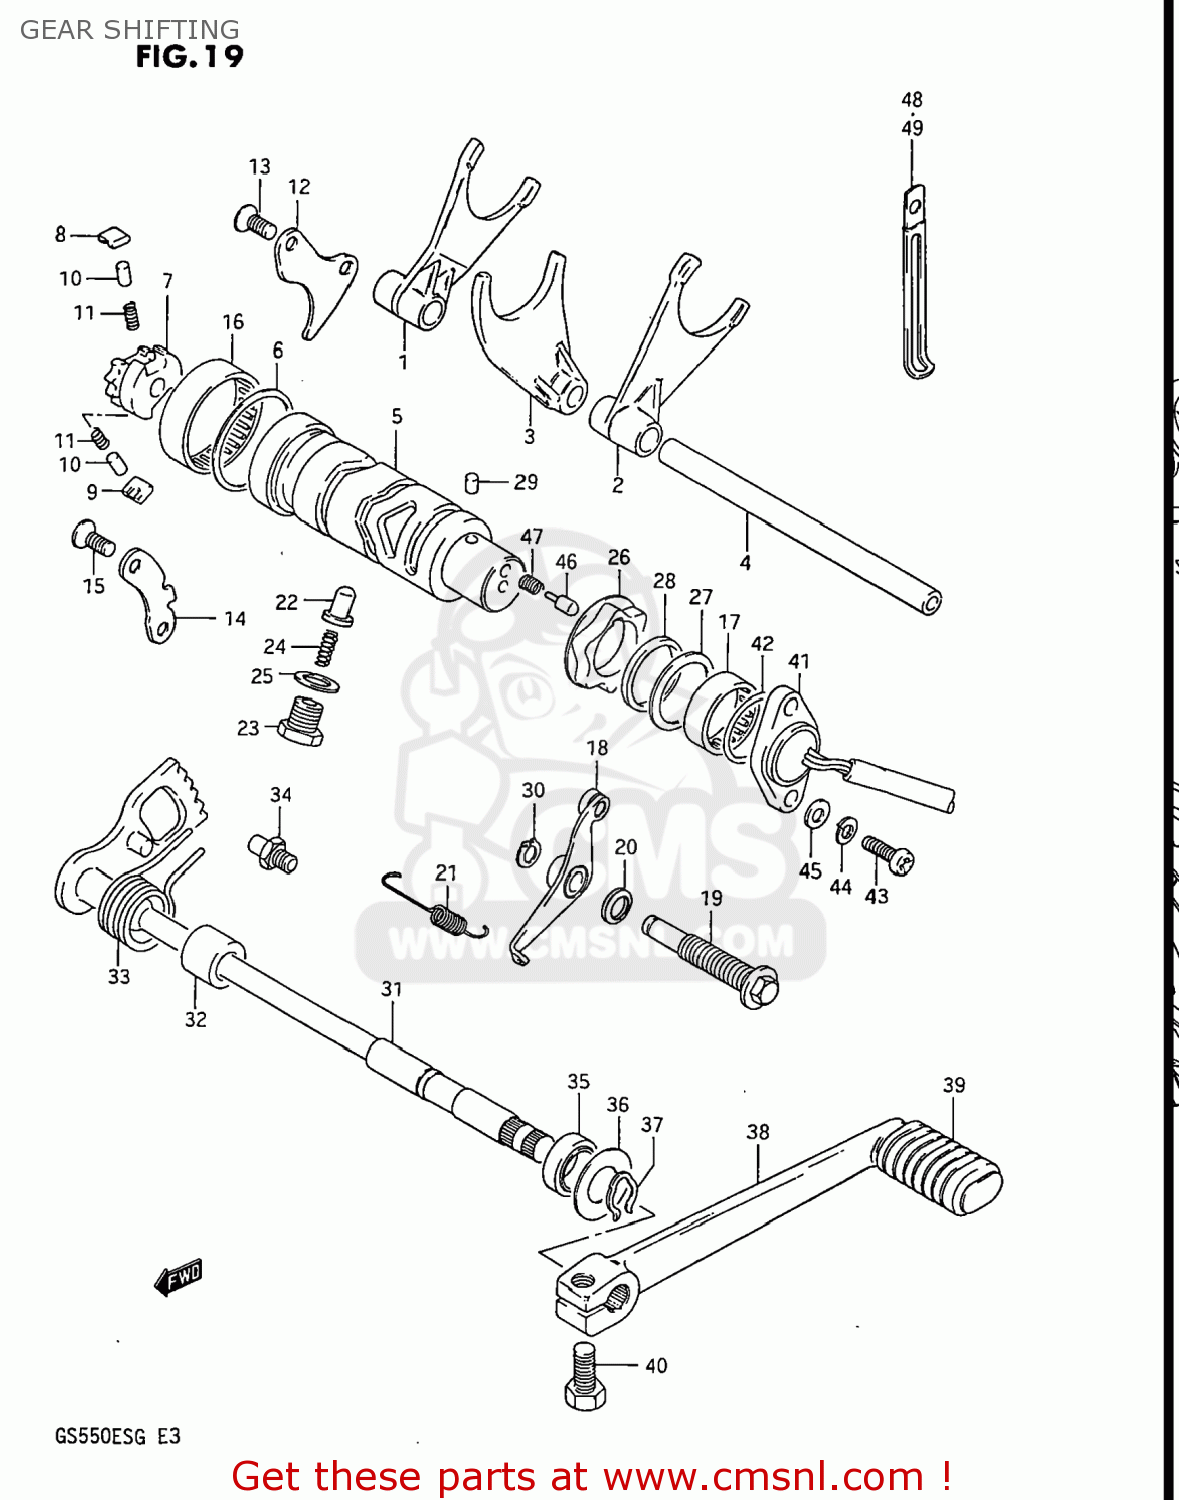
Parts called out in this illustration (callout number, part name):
1	FORK,GEAR SHIFT NO.1
2	FORK,GEAR SHIFT NO.2
3	FORK,GEAR SHIFT NO.3
4	SHAFT,GEAR SHIFT FORK
5	CAM,GEAR SHIFT
6	WASHER (40X49X1)
7	GEAR,GEARSHIFT CAM DRIVE
8	PAWL,GEAR SHIFT NO.1
9	PAWL,GEAR SHIFT NO.2
10	PIN(5X8)
11	SPRING
12	LIFTER,GEAR SHIFT PAWL
13	SCREW
14	GUIDE,GEAR SHIFT CAM
15	SCREW
16	BEARING(43X49X12)
17	BEARING(25X32X12)
18	STOPPER,GEAR SHIFTING
19	HOLDER,SHIFTING CAM STOPPER
20	GASKET(10X14X3.6) (NAS)
21	SPRING
22	STOPPER,GEAR SHIFTING
23	HOLDER,GEAR SHIFT CAM STOP SPR
24	SPRING
25	GASKET(14X19.2X2) (NAS)
26	PLATE,GEAR SHIFT CAM STOPPER
27	WASHER
28	WASHER
29	PIN 4X6
30	CIRCLIP
31	SHAFT,GEAR SHIFT
32	SPACER(12X20X15.3)
33	SPRING
34	STOPPER,GEAR SHIFT CAM
35	OIL SEAL
36	WASHER (12.5X27X1.6)
37	SPRING,RETAINER
38	LEVER ASSEMBLY,GEAR SHIFTING
39	RUBBER,PEDAL
40	BOLT
41	TERMINAL BASE ASSY,GEAR SHIFT
42	O-RING (D:2.4 ID:26.2)
43	SCREW(5X14)
44	LOCK WASHER
45	WASHER
46	PIN(5X15.5)
47	SPRING
48	CLAMP L:35
49	CLAMP
